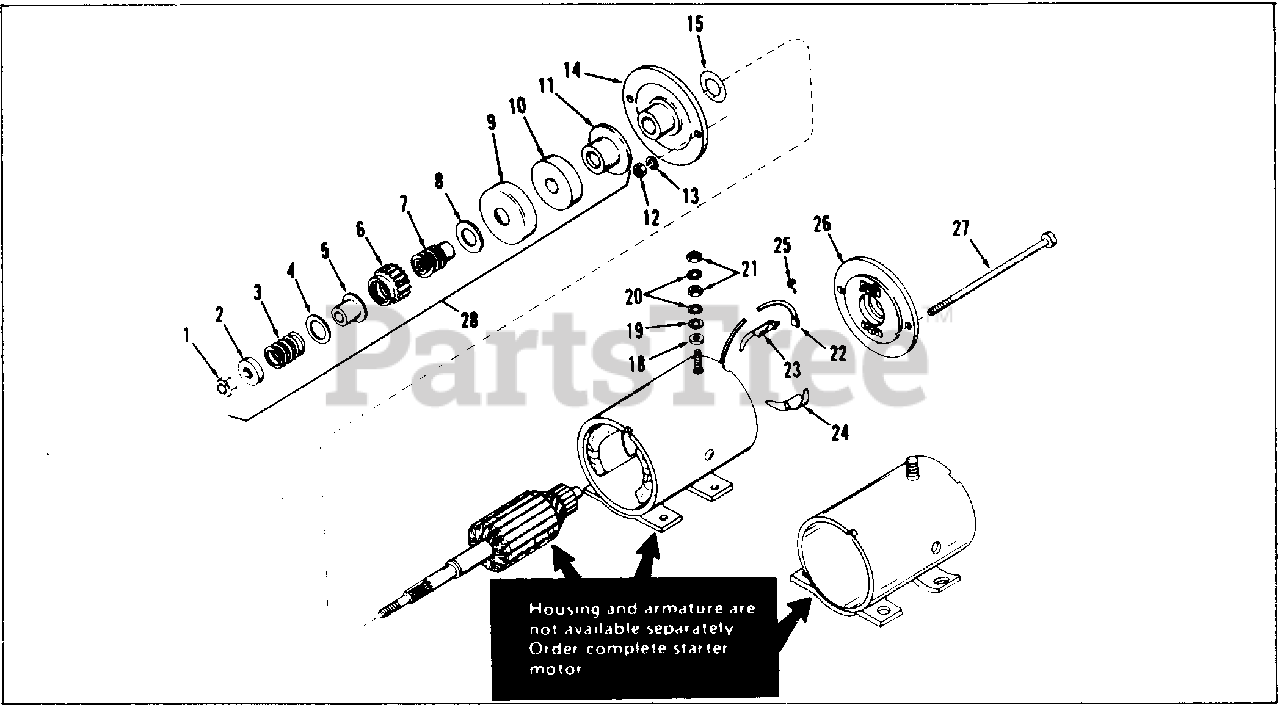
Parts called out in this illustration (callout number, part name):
1	"Nut, Elastic stop
2	Stop, Pinion
3	Spring, Anti-drift
4	Washer, Pinion
5	Sleeve, Anti-drift
6	Gear, Pinion
7	Shaft, Screw
8	Washer, Thrust
9	Cup, Cushion
10	Cushion, Rubber
11	Washer, Thrust
12	Nut, Securing
13	Washer, Lock
14	Cap Assy., Drive end (Incl. bearing)
15	Washer, Spacing (,O1O thick)
15	Washer, Spacing (.020 thick)
18	Washer, Insulating
19	Washer, Plain
20	Washer, Lock
21	Nut, Hex
23	Insulation
24	Insulation
25	Spring, Brush
26	End Cap Assy., Commutator
27	Bolt, Thru
28	Drive Assy., Complete
